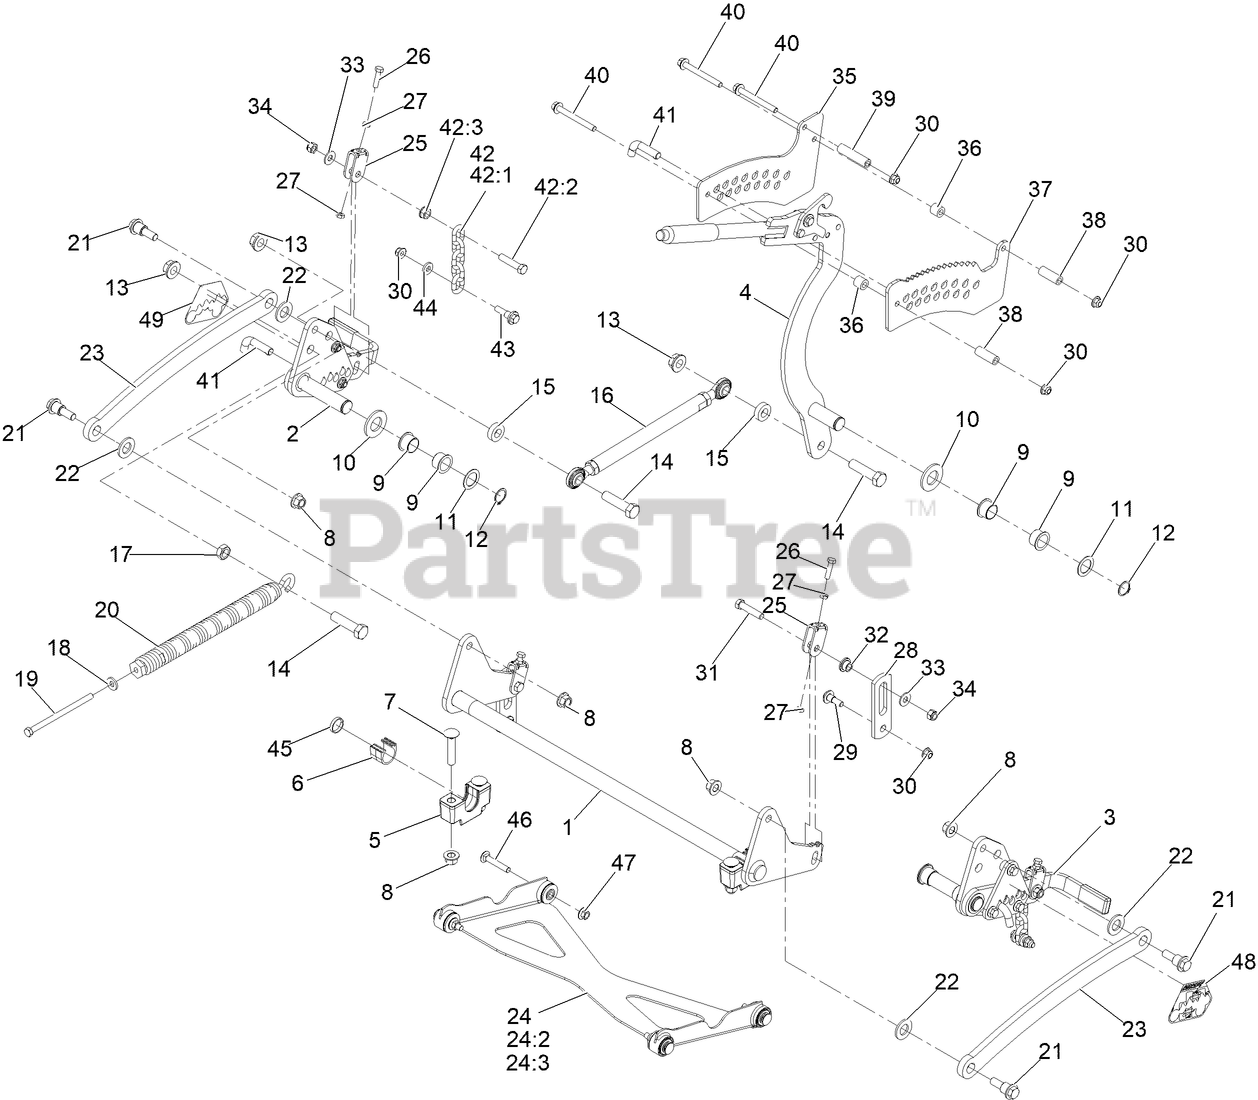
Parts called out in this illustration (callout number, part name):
1	Front Cross Shaft ASM [black]
2	Pivot ASM, HOC
3	Pivot ASM, HOC
4	HOC LEVER ASM
5	SUPPORT-CROSS SHAFT, BEARING
6	BEARING-CROSS SHAFT, FRON
7	Bolt-Carriage 1/2-13 X 2 1/2 Spl Neck
8	Nut-Lock 1/2-13
9	BUSHING
10	Washer-Flat
11	WASHER-THRUST
12	RING-RETAINING
13	NUT-HEX FLG
14	SCREW-LOCK
16	HOC LINK ASM
17	NUT-JAM
18	WASHER-BELLEVILLE
19	BOLT-TAP, HH
20	SPRING-EXTENSION
21	SCREW-SHOULDER, HHF 1/2-13 X 1.12
22	WASHER-FLAT
23	LINK-LIFT
24	DECK STRUT ASM
24:2	BUSHING-RUBBER
25	YOKE-ADJUST, DECK
26	SCREW-HH
27	NUT-JAM
28	LINK-LIFT
29	SCREW-SHOULDER, HHF
30	NUT-HF, NI
31	SCREW-HH
32	BUSHING-FLANGED
33	WASHER-FLAT
34	NUT-LOCK, NI
35	PLATE-HOC, OUTER
37	PLATE-HOC, INNER
40	SCREW-HHF
41	PIN-HOC
42	DECK LIFT CHAIN ASM
42:1	CHAIN-LIFT, DECK
42:2	SCREW-HH
43	BOLT-SHOULDER
45	SPACER-SPLIT
46	Bolt-Carriage 3/8-16 X 2 1/4
48	DECAL-DECK RAKE,LH
49	DECAL-DECK RAKE,RH
